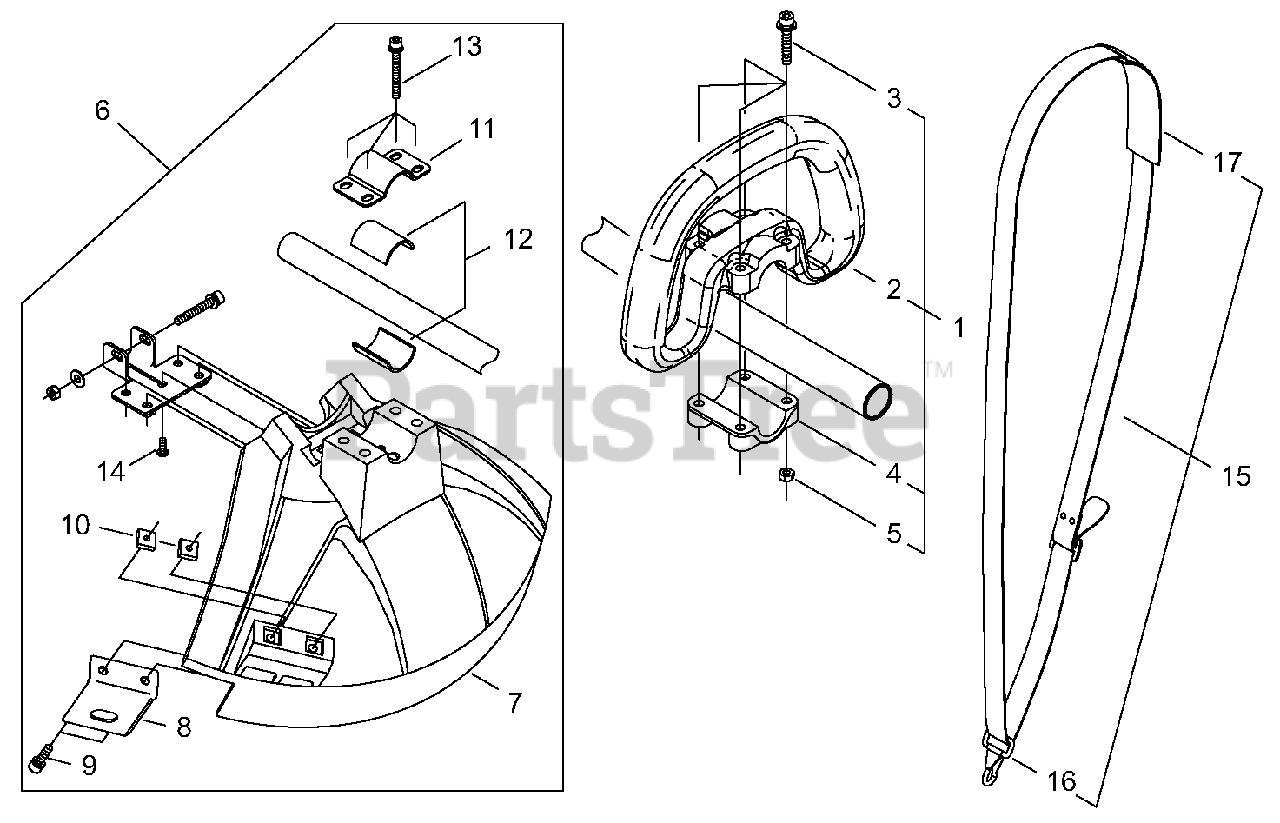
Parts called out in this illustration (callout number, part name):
1	HANDLE ASSY - FRONT
2	HANDLE - FRONT
3	SCREW
4	CAP - LOWER
5	NUT - 5
6	DEBRIS SHIELD KIT - PLASTIC
7	SHIELD, DEBRIS - BLACK
8	KNIFE, TRIMMER LINE
9	SCREW - 5X16
10	NUT - 5
11	CLAMP - UPPER
12	SPACER
13	SCREW - 5X45
14	SCREW
15	SHOULDER STRAP ASSY
16	HOOK
17	PAD, SHOULDER
